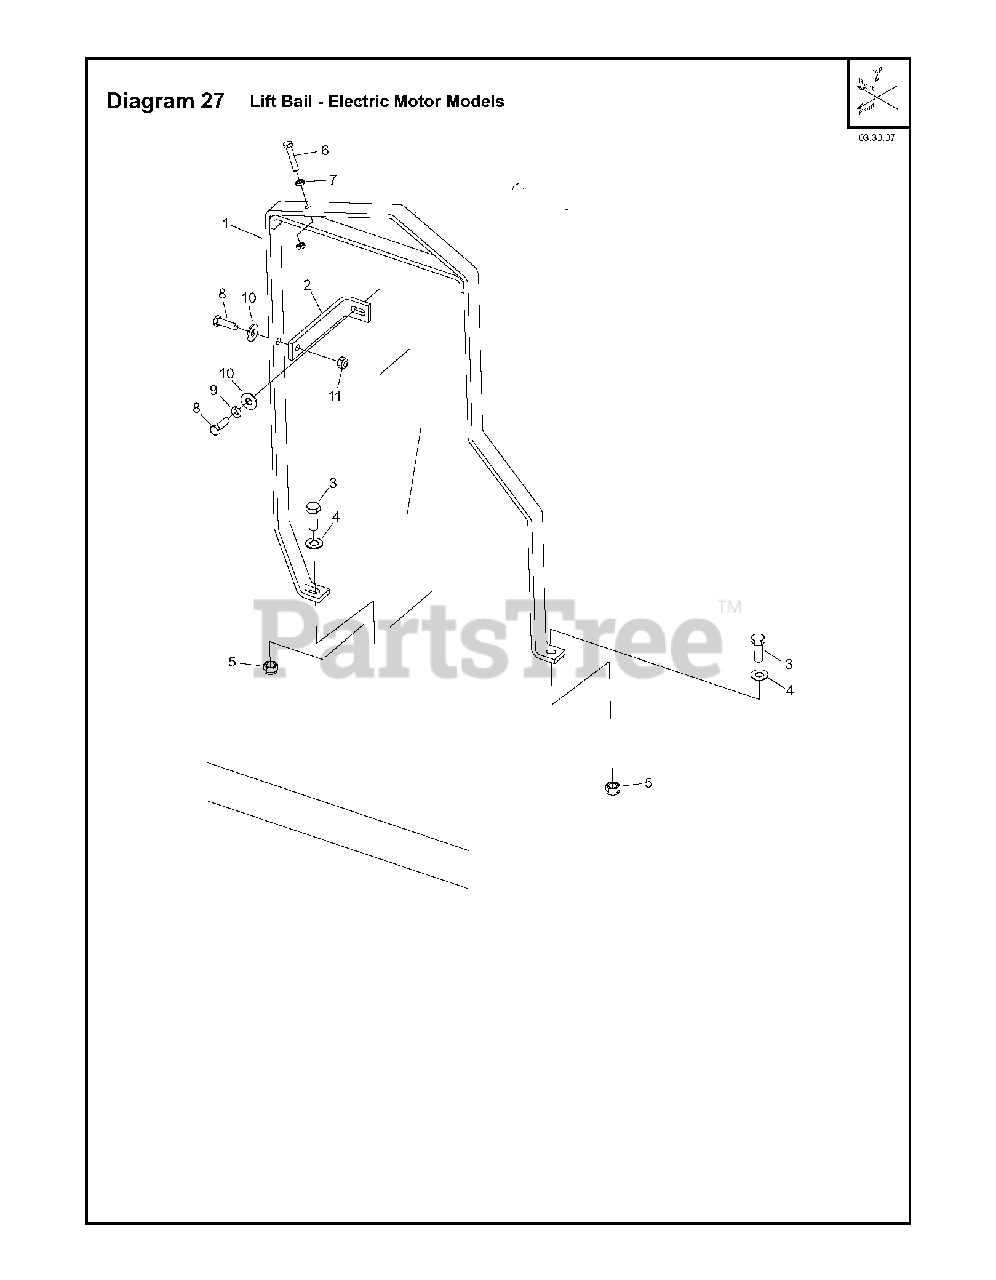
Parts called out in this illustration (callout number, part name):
1	LIFT BAIL-BLK B/M
2	BRACE. LIFT FRAME BLK
3	HHCS. M16 x 2 x 45 DIN931 Z/P
5	LOCKNUT. FIBER M16 x 2.0
6	HHCS. M10 x 1.5 x 50 DIN933 ZP
9	LOCKWASHER. SPLIT M12 DIN 127
11	LOCKNUT. FIBER M12 DIN 985 Z/P
